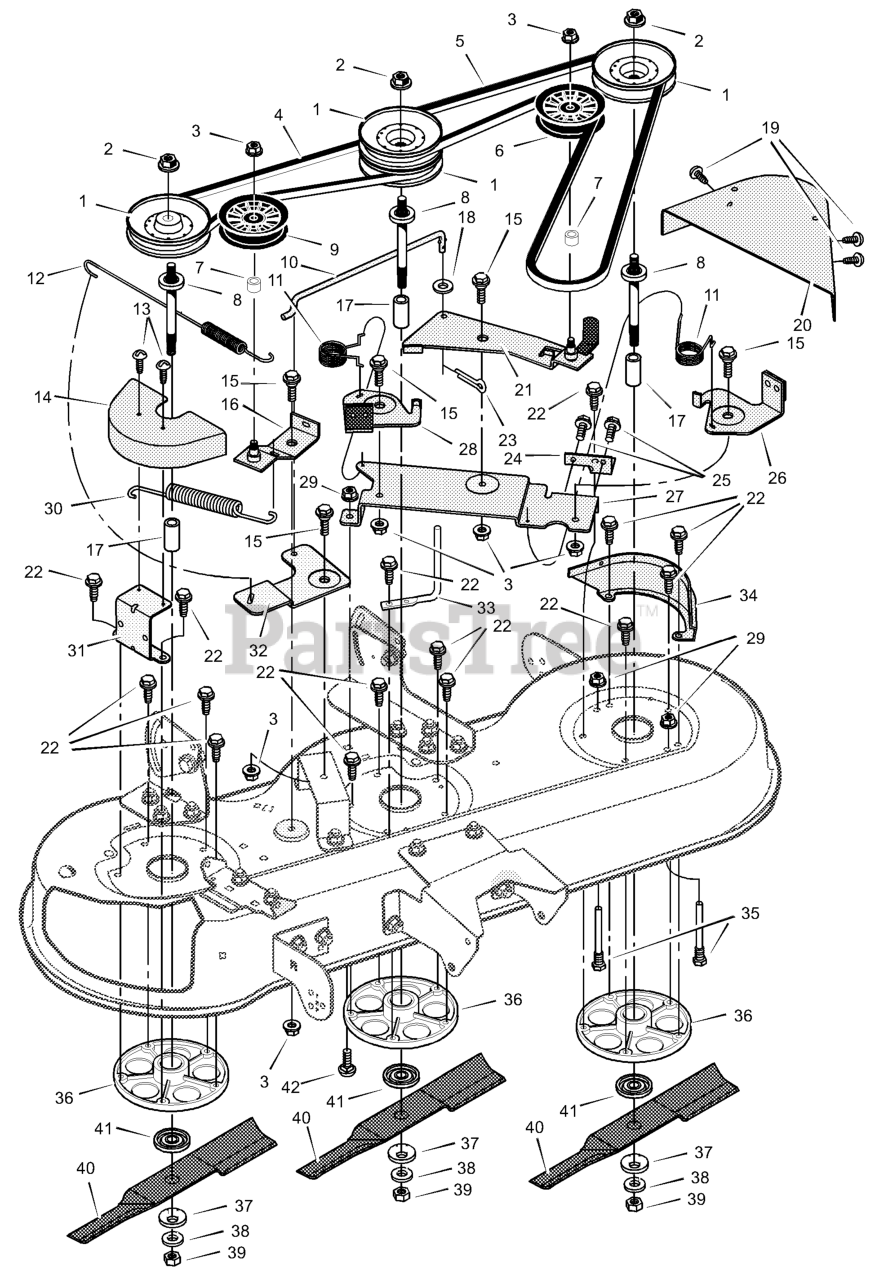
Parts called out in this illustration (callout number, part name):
1	Pulley
3	Nut
4	Belt, Secondary
5	Belt, Primary
6	Pulley, Idler
8	Jackshaft
9	Pulley, Idler
10	Link, Bell Crank
13	Screw
14	Cover, Right Pulley
15	Bolt, Shoulder
16	Arm Assembly, Idler
18	Washer
20	Cover, Left Pulley
21	Arm Assembly, Idler
22	Bolt
23	Pin, Cotter
24	Bracket, Brake Plate
26	Brake Assembly, Left
27	Plate, Brake Arm
28	Brake Assembly, Center
29	Nut, Flange
31	Bracket, Cover
32	Bell Crank
33	Guide, Belt
34	Bracket, Pulley Cover
35	Guide, Belt
36	Housing, Jackshaft
39	Nut, Blade
41	Adapter, Blade
42	Bolt, Carriage
